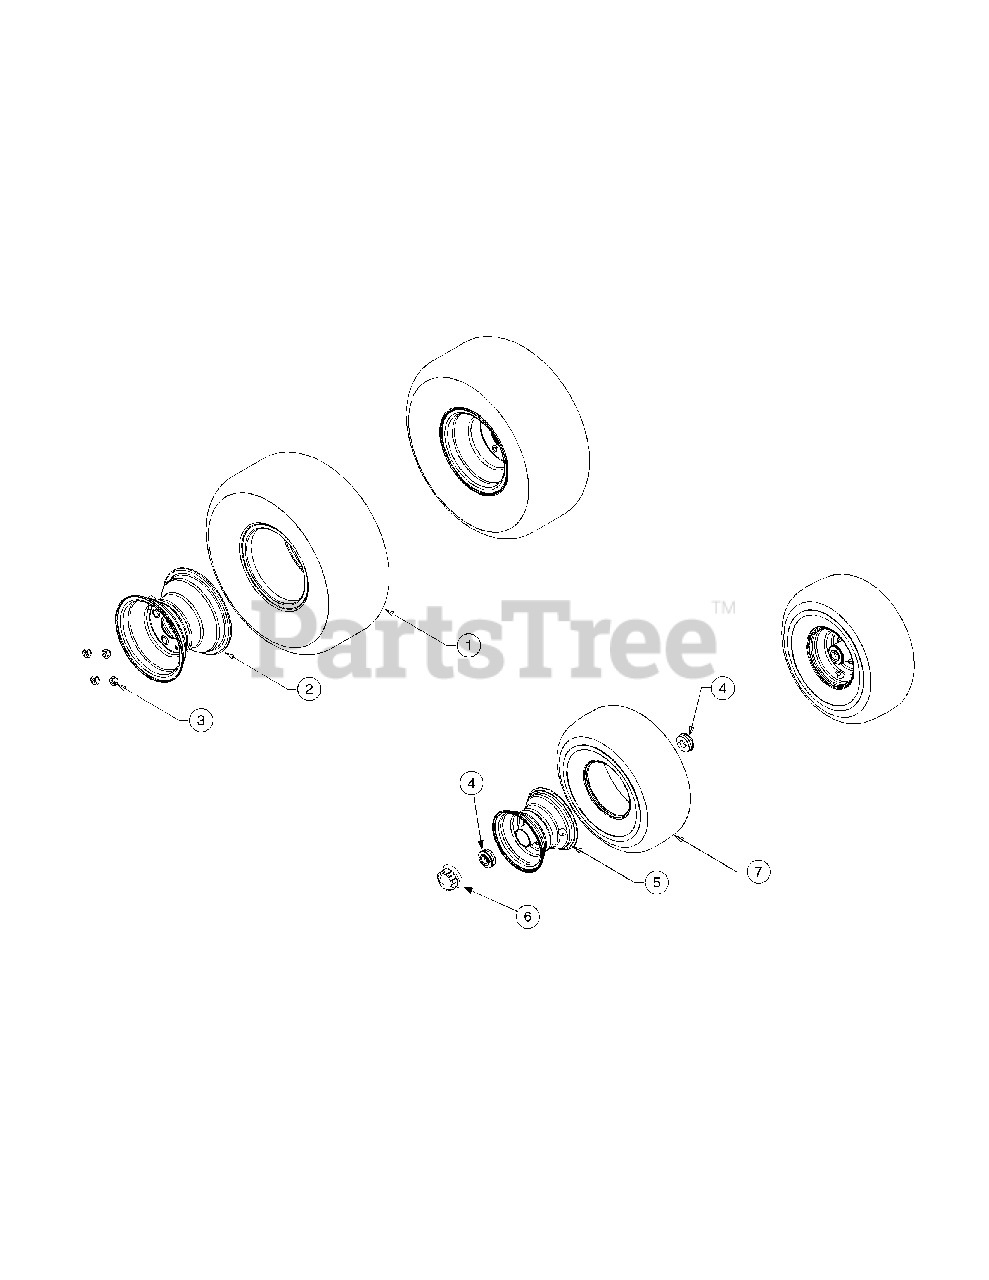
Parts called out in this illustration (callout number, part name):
2	Rim Assembly, 12.0 x 7.0 (4-Lug)
3	Lug Nut, 7/16-14
4	Bearing, Ball, .75 ID x 1.75 OD
5	Rim Assembly, Bead Lock, 8 x 5.38 (Included, Bearings and Valve)
6	Hub Cap
